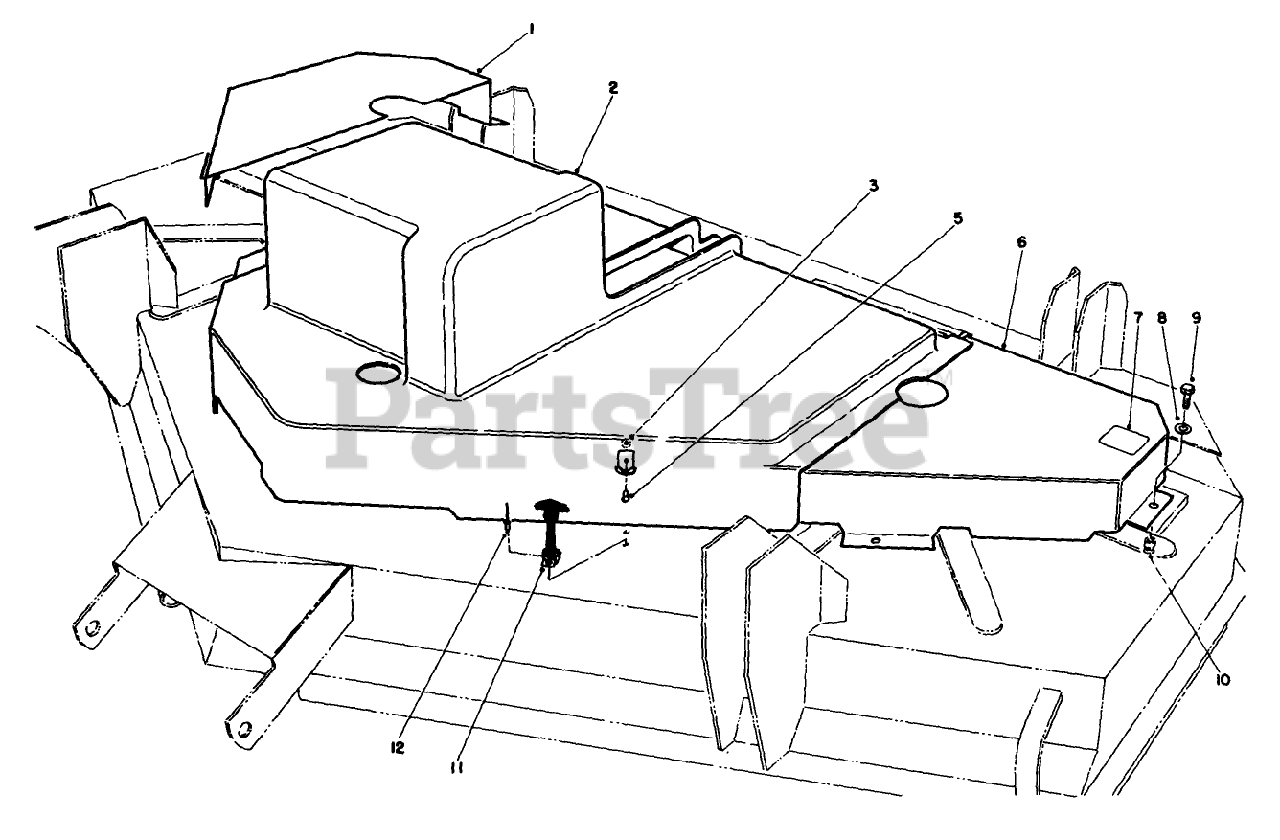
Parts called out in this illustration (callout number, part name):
1	R/H BELT COVER R/B
2	CENTER COVER
3	WASHER
5	Rivet-Pop
6	L/H BELT COVER R/B
7	DECAL-NO STEP
8	WASHER-FLAT
9	1/4-20 X 5/8 CAPSCREW
10	INSERT-THREADED
11	FLEX DRAW LATCH ASM
12	RIVET-POP
